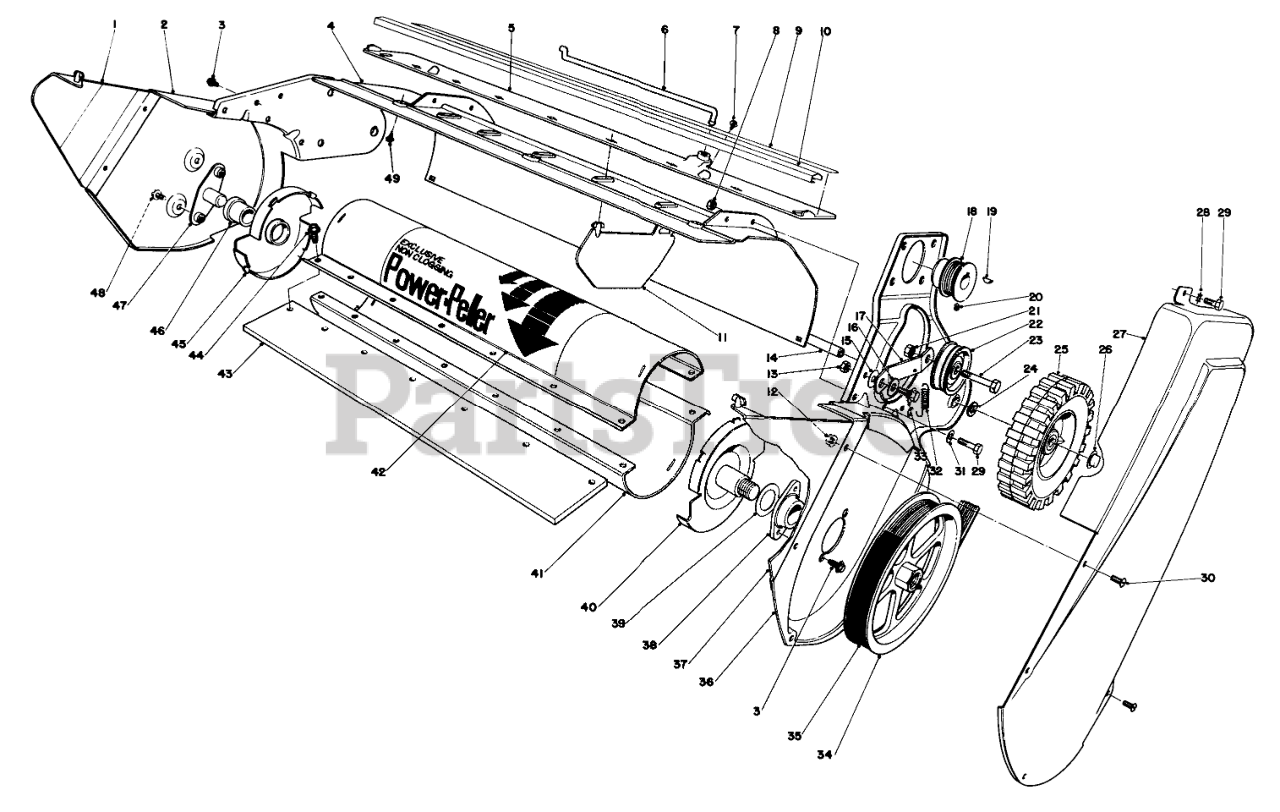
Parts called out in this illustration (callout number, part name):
1	Side Plate Right
2	Vane-Outside R.H.
3	1/4-20X1/2 THDG SEMS
4	Housing
5	Vane Mount
6	Linkage-Vane Adjustment
7	10-16 X 3/8 THDG SCREW
8	NUT-LOCK, CONE
9	Decal Warning
10	Moulding
11	Vane
12	NUT-LOCK, FLANGE
13	NUT-LOCK, CONE
15	WASHER-PIVOT
16	WASHER
17	Idler Arm
18	Pulley Engine
20	SCREW-SET, HSH
21	NUT-LOCK, CONE
22	PULLEY IDLER
23	SCREW-HH
24	WASHER-FLAT
25	WHEEL
26	RETAINER-PUSH ON
27	Drive Cover
28	WASHER-LOCK/EXT
29	SCREW-HH
30	SCREW-PTH
31	WASHER-FLAT
32	IDLER SPRING
33	SCREW-SHOULDER
34	Rotor Pulley
35	Belt
36	Side Plate Left
37	Vane-Outside L.H.
38	Rotor Bearing
39	WASHER-THRUST
40	Drive Shaft & End Cap
41	ROTOR SHELL
42	Decal-Power Peller
43	ROTOR BLADE
44	SCREW-TAP
45	End Cap R.H. (Incl. Ref. #46)
46	ROTOR BUSHING
47	Rotor Shaft
48	1/4-20 X 3/8 SEMS SCR
49	SCREW-HWHTF
